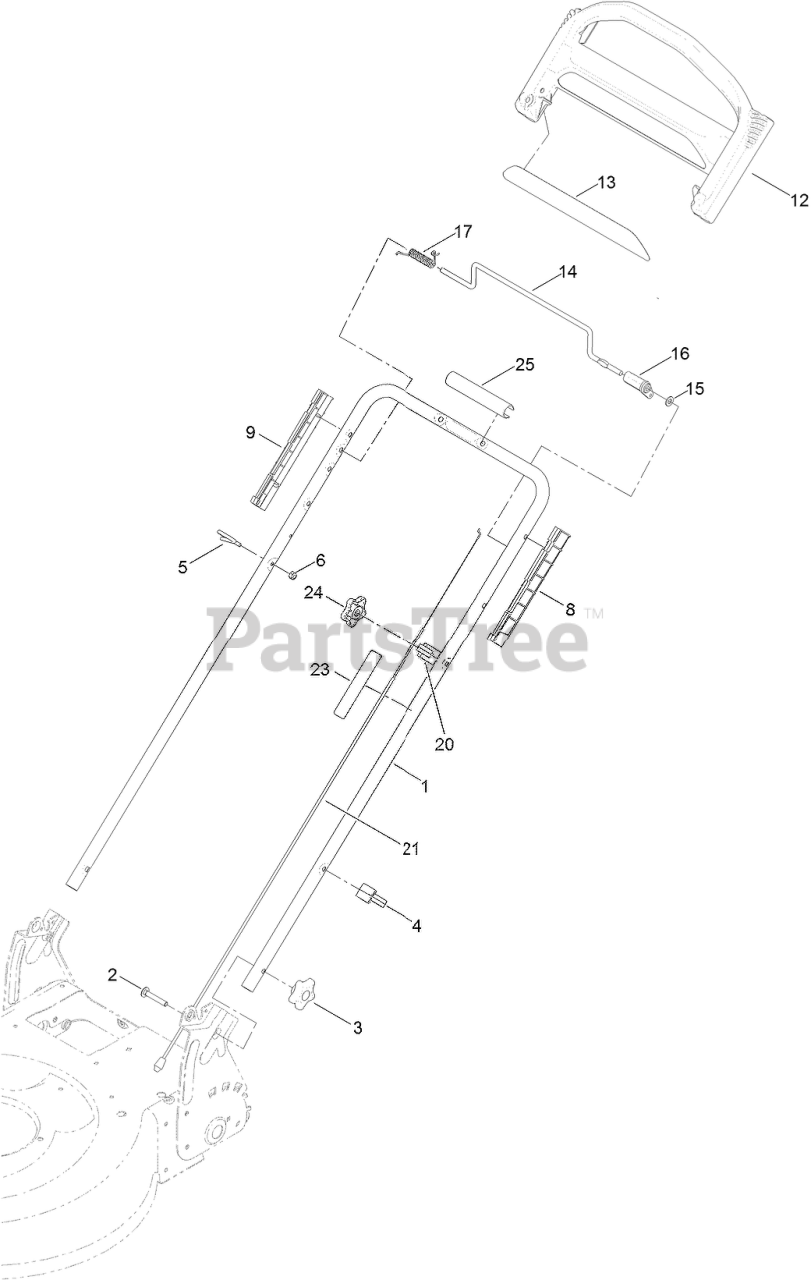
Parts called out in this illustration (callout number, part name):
2	Screw-CARR
3	KNOB-HANDLE
4	GUIDE-CABLE
5	GUIDE-ROPE
6	NUT-LOCK, NI
8	GUIDE-LH
9	GUIDE-RH
12	HANDLE-CONTROL
14	BAR-CONTROL, TRACTION
15	WASHER-PLAIN
16	LEVER-TRACTION
17	Spring-Torsion
20	ANCHOR-CABLE
21	CABLE-TRACTION
23	DECAL-TRACTION, ADJUST
24	KNOB-HANDLE, LOCKING
25	COVER-HANDLE
